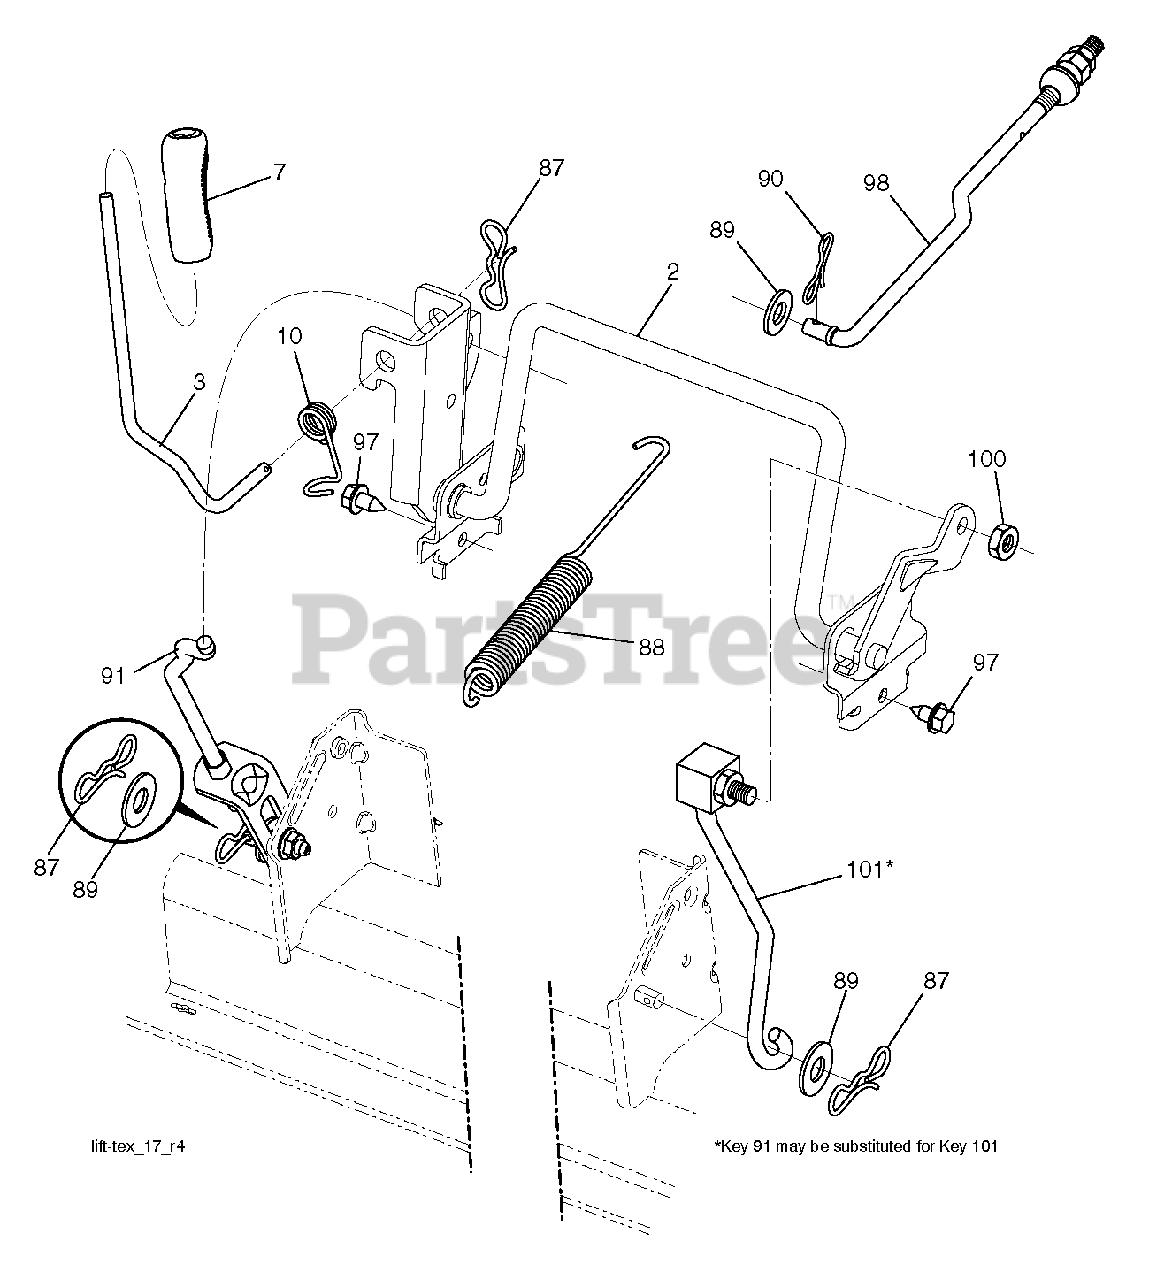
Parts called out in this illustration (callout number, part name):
2	SHAFT LIFT DECK WELD
3	LEVER.LIFT.HANDLE.LT
7	GRIP.HANDLE.LIFT.PVC.BLACK
10	SPRING.TORSION.LIFT.HANDLE
87	PIN.COTTER.7/16.BOW TI.
88	SPRING.DK.LIFT.97/107.TXCRDII
89	WASHER.CLEAR.ZINC
90	PIN.COTTER.5/16.BOW TI
91	LINK.ASM.LIFT.REAR
98	LINK.ASM.SUSP.FRONT.MW
100	LOCKNUT
101	LINK.ASM.LIFT.FIXE.38/42/46"
